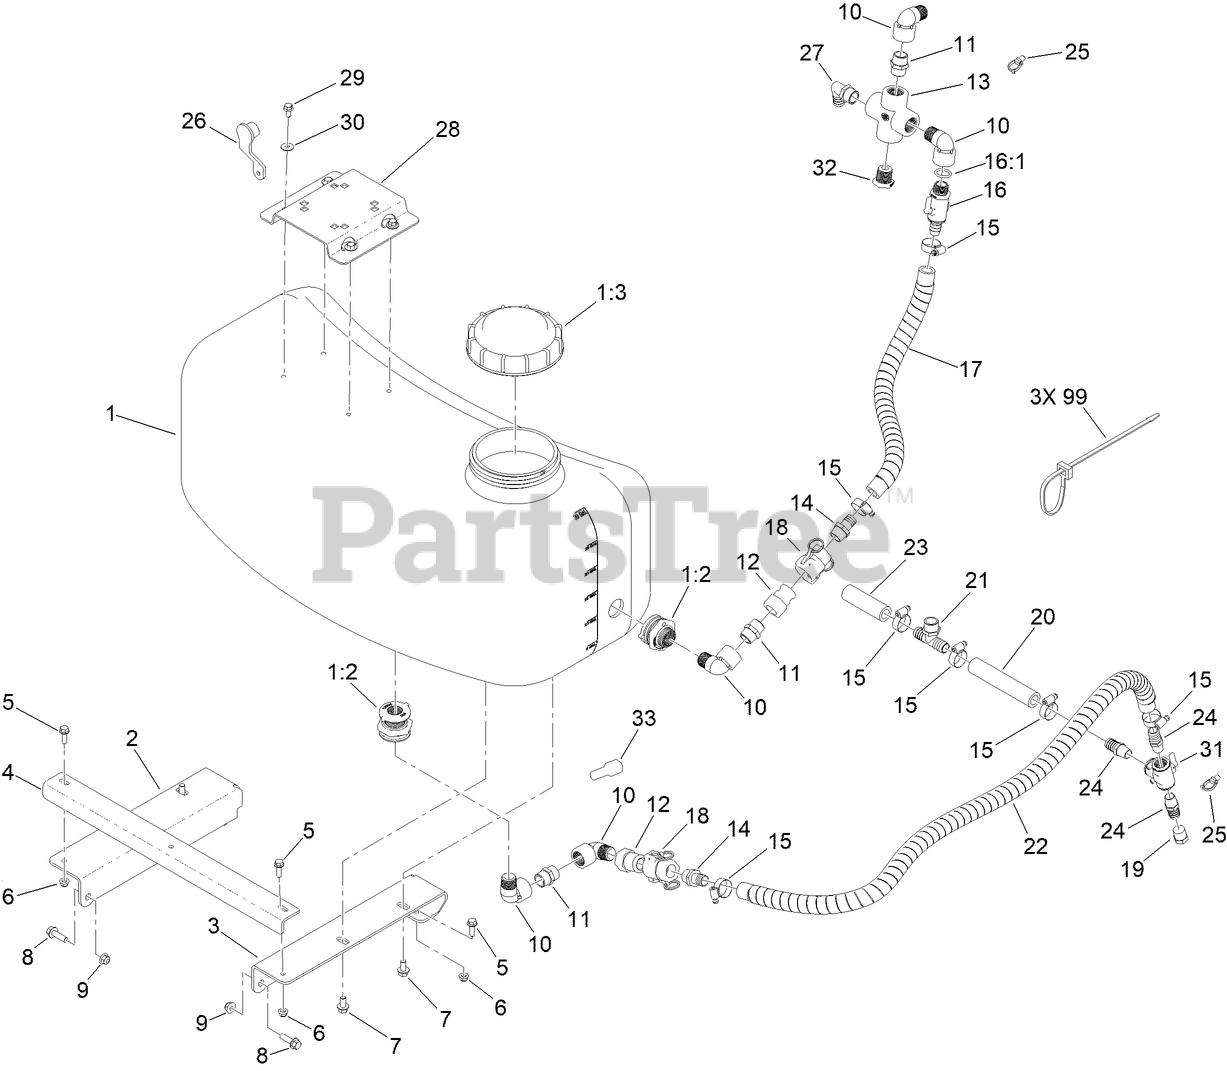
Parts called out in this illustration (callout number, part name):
1	ASM-TANK, 30 GAL
1:2	FITTING-BULKHEAD
1:3	CAP-TANK, SPRAY
2	MOUNT-TANK, RT
3	MOUNT-TANK, LT
4	SUPPORT-TANK, FRONT
5	SCREW-HHF
6	NUT-HEX FLANGE
7	SCREW-HHF
8	SCREW-HHF
9	NUT-HEX FLANGE
10	ELBOW-90 DEG
11	FITTING-NIPPLE
12	ADAPTER-MALE
13	FITTING-CROSS
14	HOSEBARB
15	CLAMP-HOSE
16:1	O-RING, -213
17	HOSE-SPRAY, WRAPPED
18	COUPLER-FEMALE
19	PLUG-VALVE
20	HOSE-SPRAY
21	FITTING-TEE
22	HOSE-SPRAY, WRAPPED
23	HOSE-SPRAY
24	FITING-STRAIGHT
25	CLIP-TIE
26	CRANK-REEL
27	FITTING-ELBOW, 90
28	MOUNT-HOSE REEL
29	SCREW-HHF
30	WASHER-BELLEVILLE
31	Carburetor, Complete (Incl. Ref. #33)
32	FITTING-PLUG
33	BOOT-RECEPTACLE
99	TIE-CABLE
